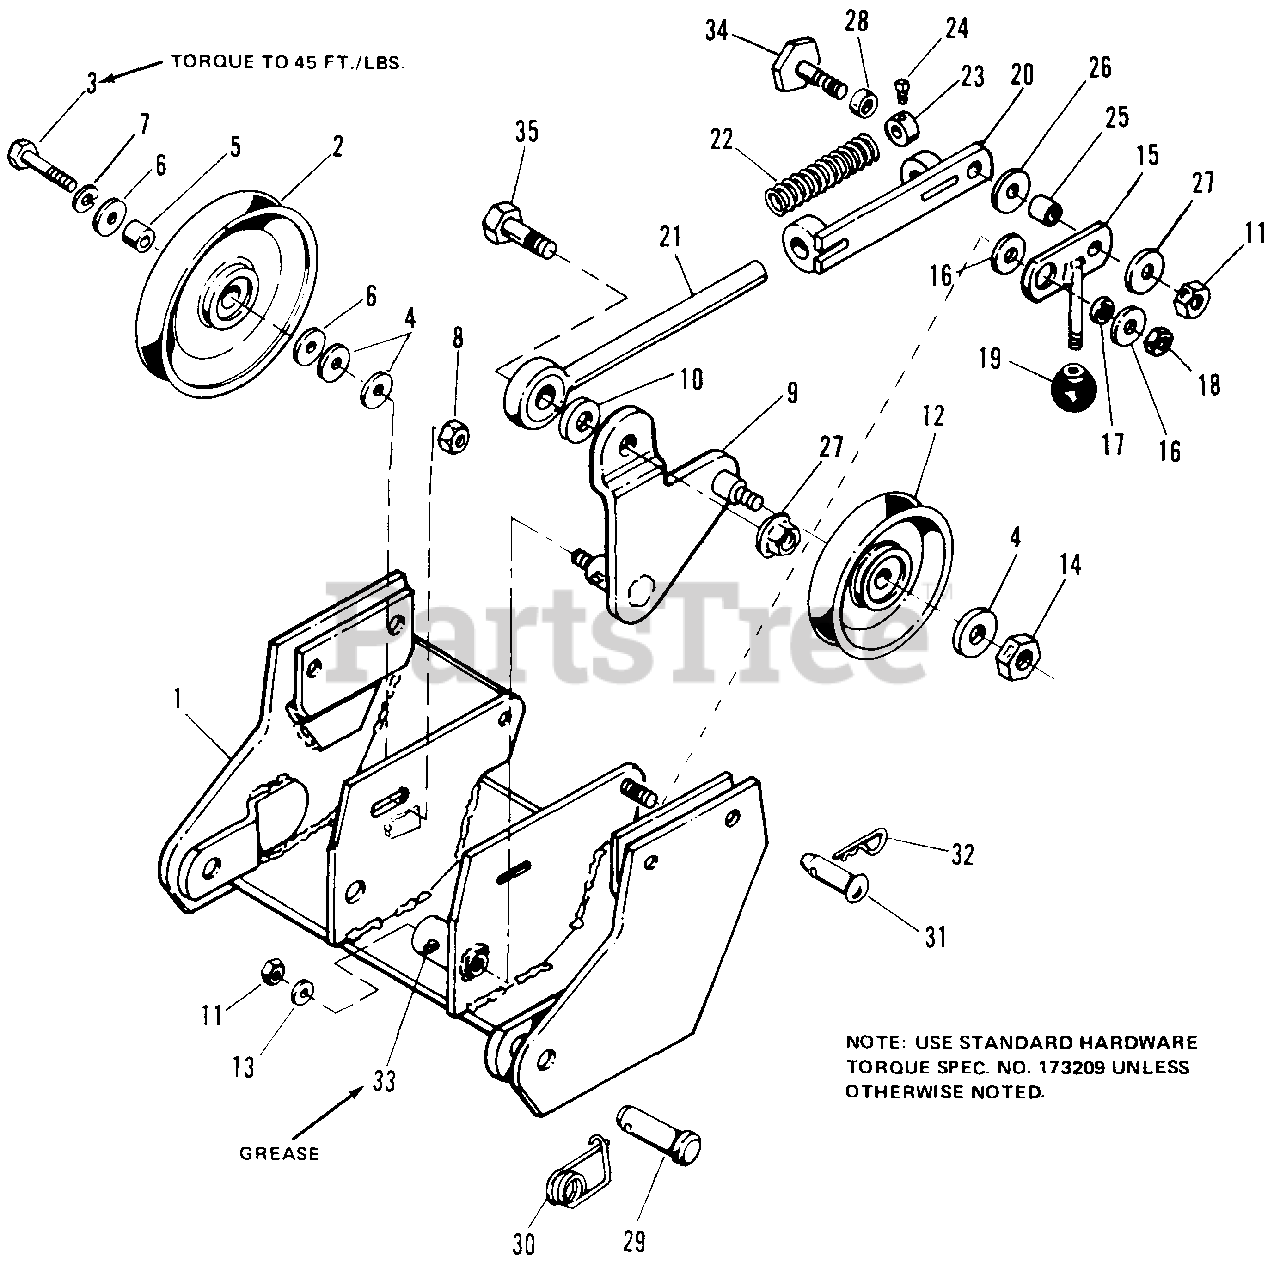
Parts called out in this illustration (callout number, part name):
1	SUPPORT ASSY
3	CAPSCREW, Hex Hd., 3/8-24 x 1-3/4, Gr. 8
4	WASHER, Plain, 5/16
7	LOCKWASHER, Spring, 3/8
8	NUT, Flange, Whiz Lock, 3/8-24
9	LEVER ASSY
10	WASHER, Plain, 1/2
11	NUT, Hex, Full Lock, 3/8-16
14	NUT, Hex, Full Lock, Jam, 1/2-13
15	LEVER ASSY
16	WASHER, Plain, 3/8
18	NUT, Hex, Lock, Jam, 1/2-13
20	GUIDE ASSY, Rod
21	BOLT, Eye
23	COLLAR, Set
24	SCREW, Set, Sq. Nk., Cup Pt., 1/4-20 x 3/8, Gr. 8
26	WASHER, Special
27	NUT, Hex, Flange, Whix Lock, 3/8-16
29	PIN, Yolk
30	CLIP, Pin Safety
32	CLIP, Spring
33	FITTING, Lube, Dr. Type, 1/2
35	BOLT, Shoulder
